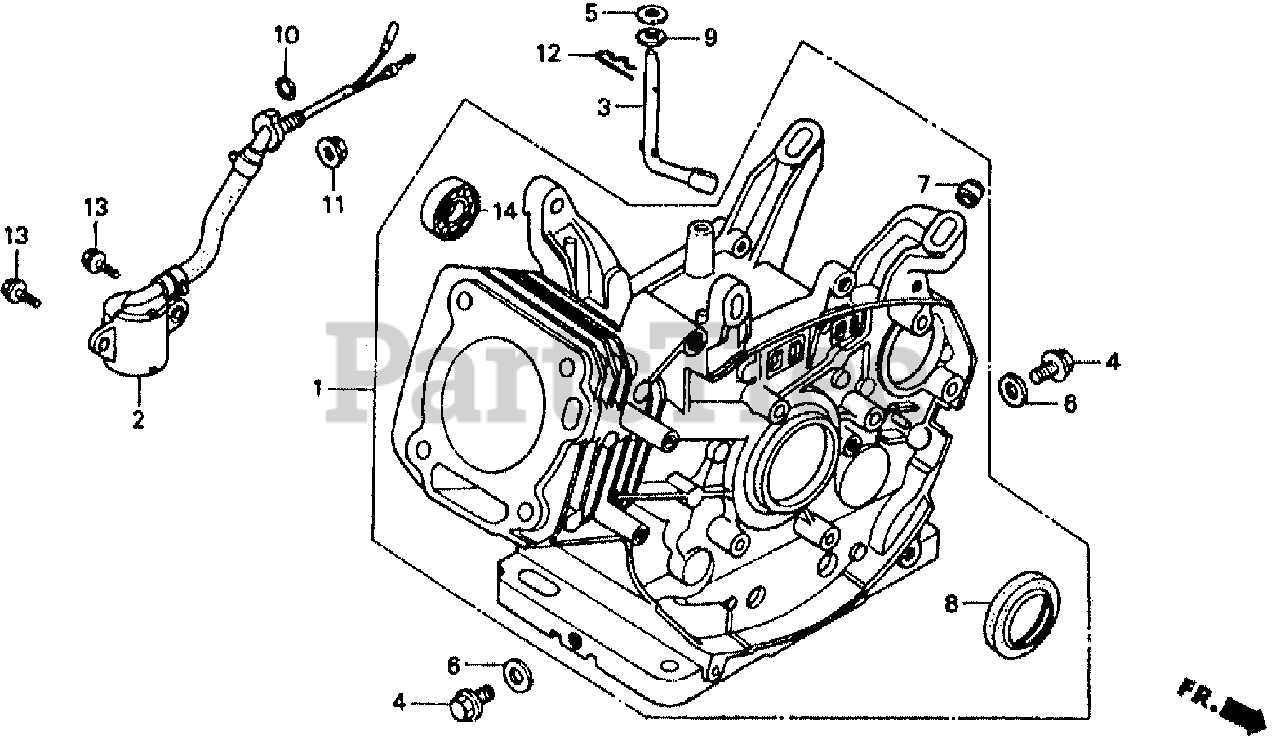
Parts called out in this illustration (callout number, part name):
1	CYLINDER ASSY. (STD)
3	SHAFT, GOVERNOR ARM
4	BOLT, DRAIN PLUG
5	WASHER (8.2X17X0.8)
6	WASHER, DRAIN PLUG (12MM)
7	PLUG, SEALING
8	OIL SEAL (30X46X8)
9	OIL SEAL (8X14X5)
12	PIN, LOCK (8MM)
